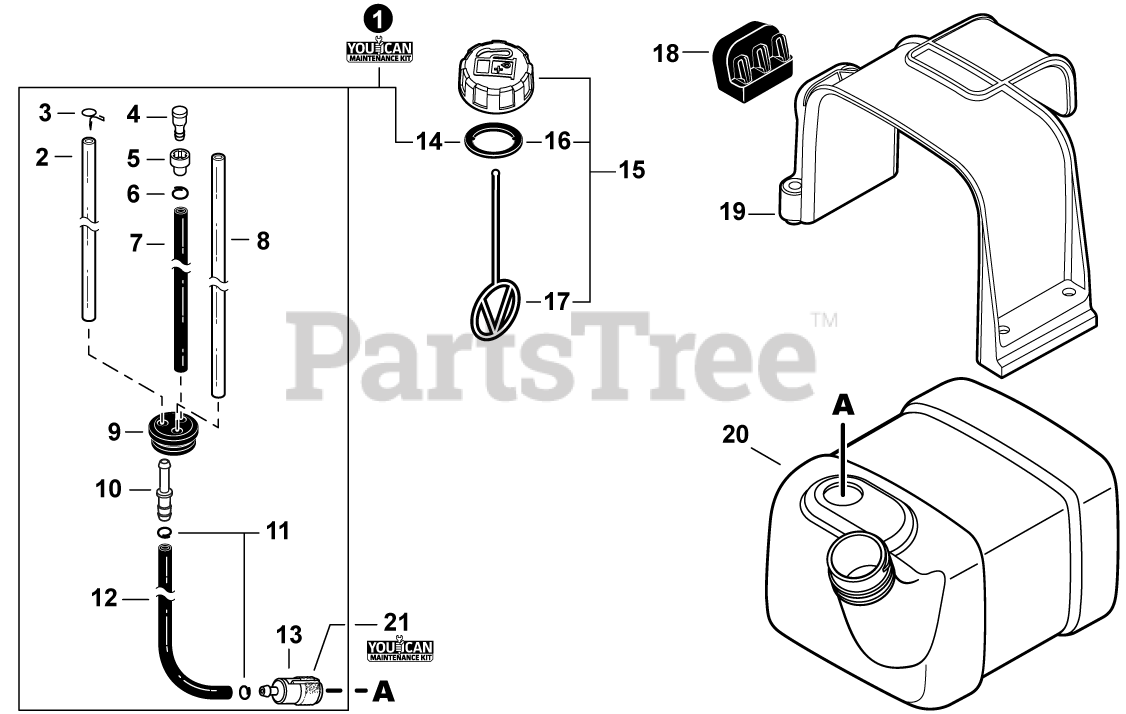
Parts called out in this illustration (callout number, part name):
1	FUEL SYSTEM KIT - YOUCAN
2	PIPE, FUEL 3.5x6x205 CLEAR
3	CLIP, SPRING 5.2
4	VENT ASSY
5	HOLDER, VENT
6	CLIP 6.5 MM
7	PIPE, FUEL 3x6x40 BLACK
8	PIPE, FUEL 3x6x180 YELLOW
9	GROMMET, FUEL
10	CONNECTOR, PIPE 5x3.5
12	PIPE, FUEL 3x5x120 BLACK
13	FILTER, FUEL
14	GASKET, FUEL CAP
15	CAP ASSY, FUEL
16	GASKET, FUEL CAP
17	CONNECTOR, CAP L= 100 MM
18	CUSHION
19	RETAINER, FUEL TANK
20	TANK, FUEL
21	TUNE-UP KIT - YOUCANT
